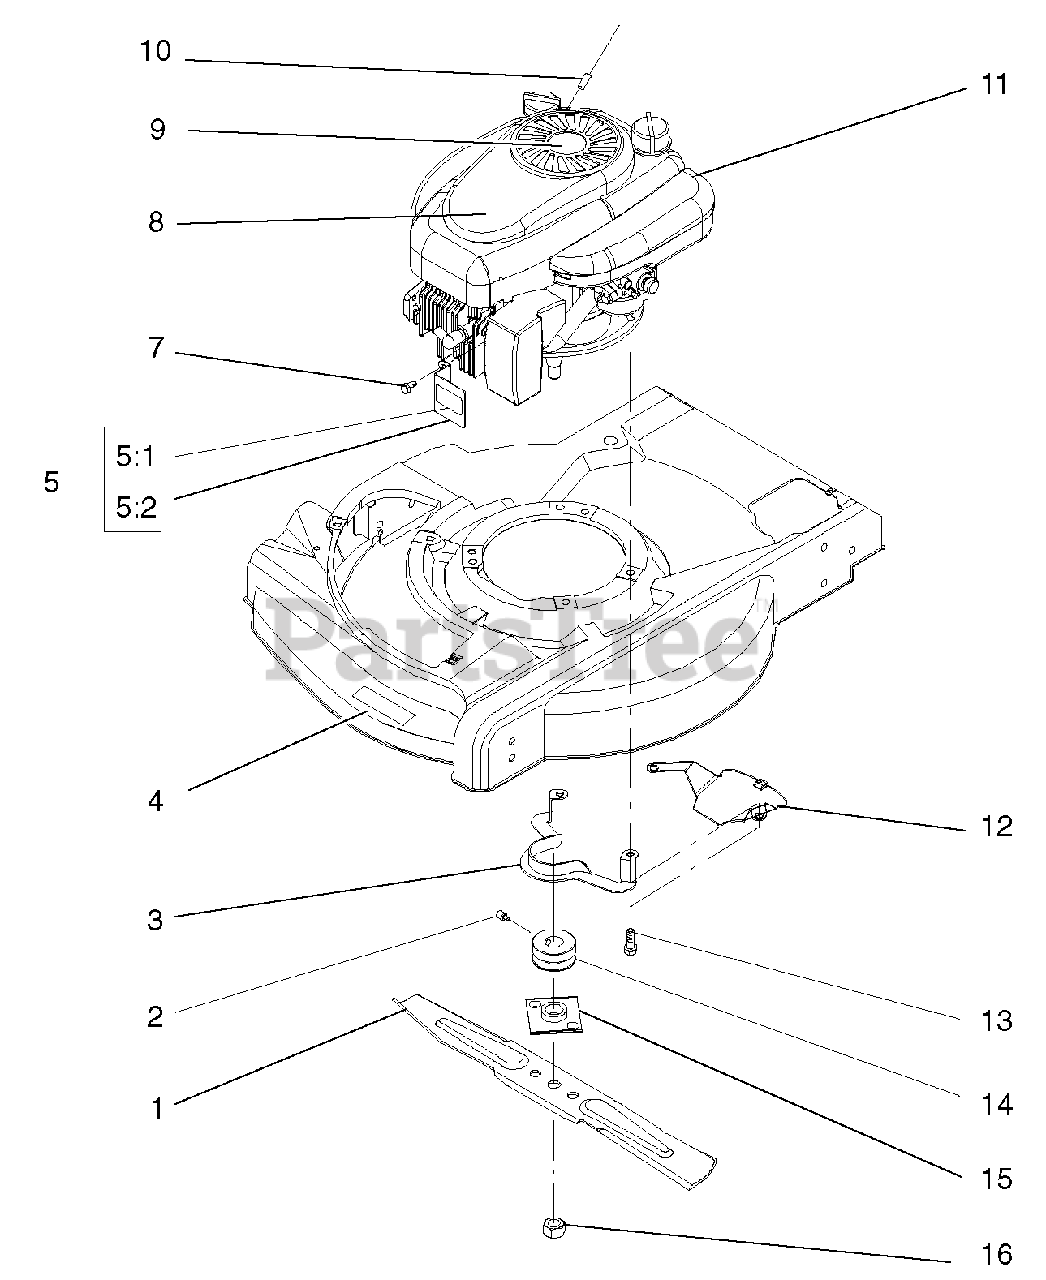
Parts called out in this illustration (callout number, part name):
2	Screw-Set,Cone Point
3	Guide-Belt
4	Decal-Deck
5	ASM-Guard,Muffler
5:1	Decal-Surface, Hot-International
5:2	Guard-Muffler
8	Applique
9	Decal-Recoil,5hp
10	Stop-Rope
11	Engine (Tecumseh Lev115-350181e)
12	Shield-Grass
13	Screw-Taptite W/Patch
15	Blade Retainer ASM
16	Nut-Blade
